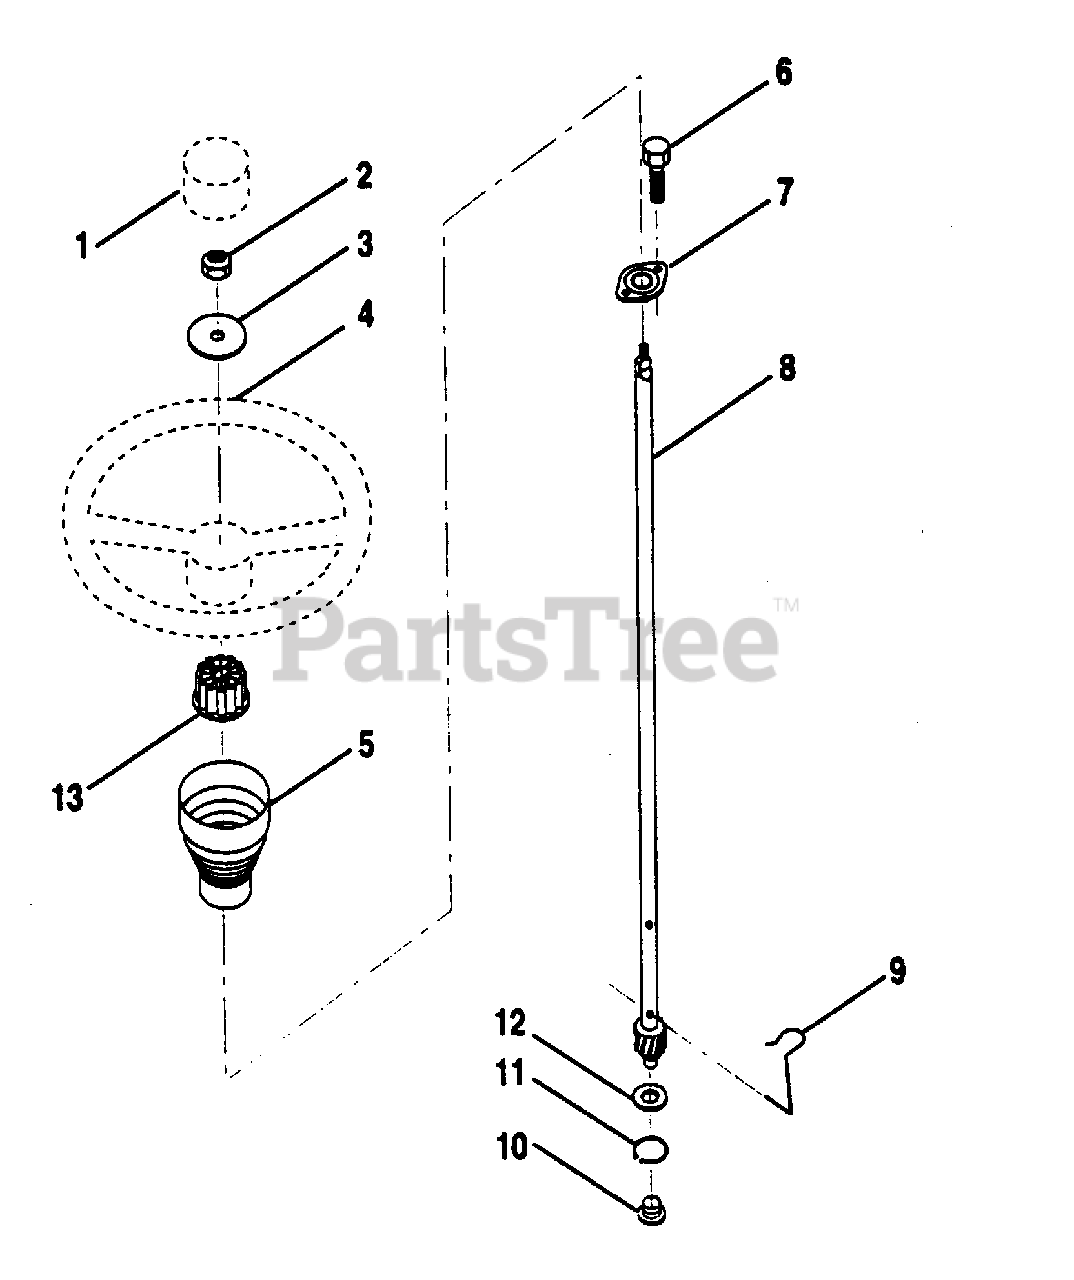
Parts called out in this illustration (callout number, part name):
1	Insert, Wheel, Steering (AYP part number)
2	Nut, Lock 3/8-24 UNF (AYP part number)
3	Washer 12/32 x 2-3/8 x 8 Ga. (AYP part number)
4	Wheel, Steering (AYP part number)
5	Sleeve, Steering (AYP part number)
6	Screw, Hex #10-16 x 1/2 TY-B (AYP part number)
7	Bushing, Steering (AYP part number)
8	Shaft, Steering (AYP part number)
9	Clip, Steering (AYP part number)
10	Bushing, Lower, Steering (AYP part number)
11	Ring, Retaining (AYP part number)
12	Washer 21/32 x 1 x 16 Ga. (AYP part number)
13	Adaptor, Wheel, Steering (AYP part number)
